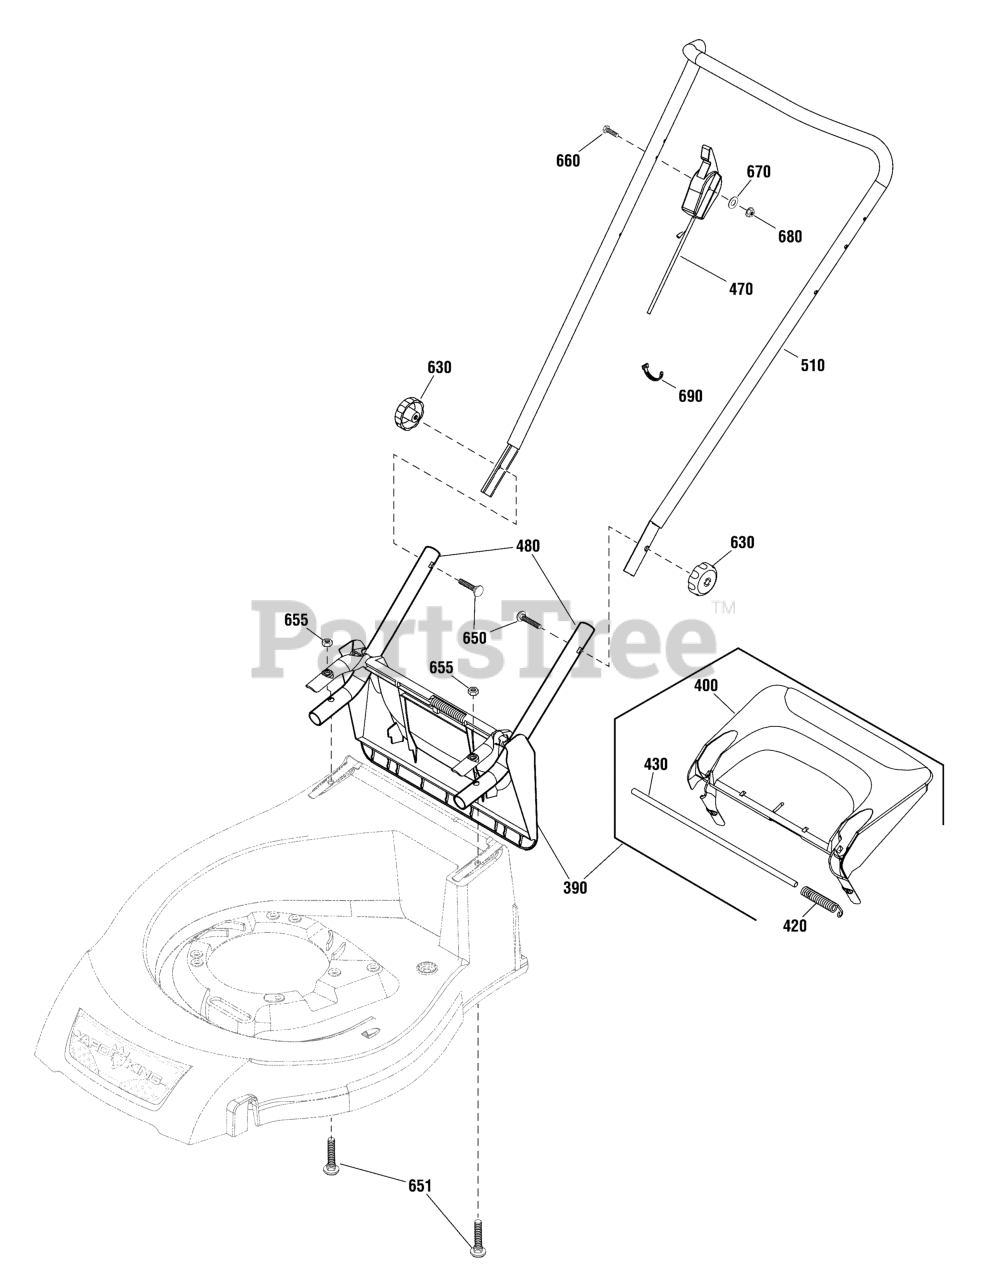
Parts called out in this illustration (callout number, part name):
390	REAR FLAP ASSEMBLY
400	REAR FLAP
430	ROD
470	THROTTLE CONTROL
480	HANDLE, Lower, Classic
510	HANDLE, Upper, Comfort Grip
630	KNOB, Handle
650	BOLT 5/16 UNC x 1-3/4
651	SCREW, Lower Handle
660	SCREW, Pan Head Phillips, 10-24 x 1-3/4
670	WASHER, 3/16 ID x 5/8 OD
680	NUT, 10-24
690	TIE, Cable
